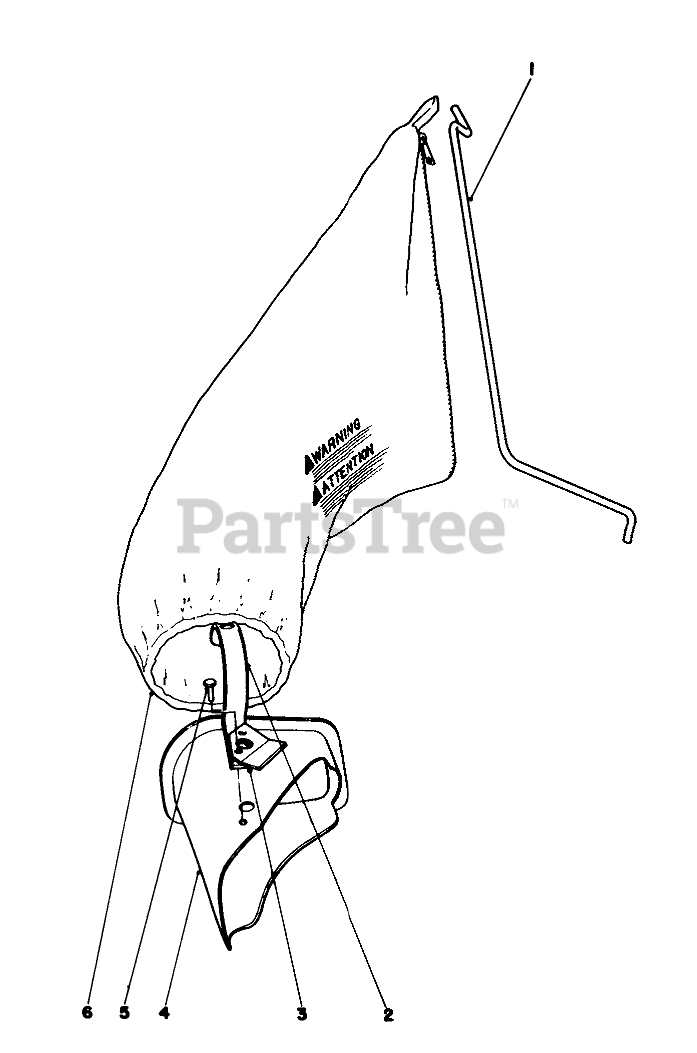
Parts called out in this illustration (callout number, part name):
1	BAG HANGER ROD
2	BAG CHUTE HANDLE
3	Stop Deflector
4	Grass Chute (Incl. Ref. #2, 3 & 5)
5	Rivet Semi Tubular
6	BAG REPLACMNT44-0540
